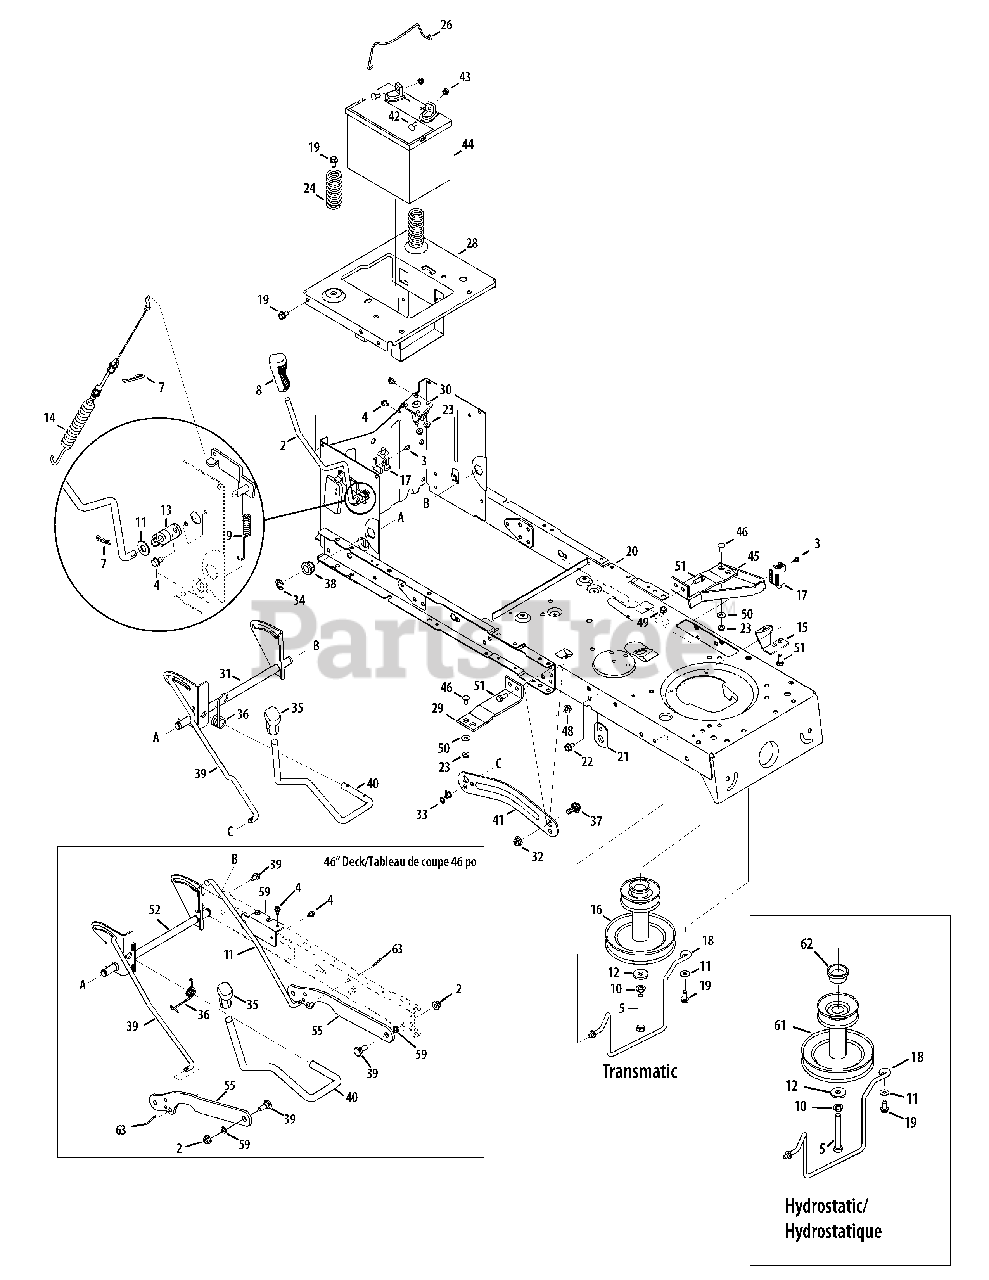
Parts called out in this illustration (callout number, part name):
2	PTO Handle
3	Shoulder Scr #10-16 x .50" Lg.
4	Hex Wash S-Tapp Scr 1/4-20 x .50
5	Hex Hd. Cap Scr. 7/16-20 x 3.25 Gr. 5
6	Frame Brace Bracket
7	Bow Tie Cotter Pin
8	Handle Grip 3/8
9	Extension Spring
10	Lockwasher 7/16 ID
11	Flat Washer .385 ID x .87 OD x .06
12	Flat Washer .450 x 1.25 x .164
13	PTO Bearing
14	Deck Engagement Cable
15	Frame Support Bracket
16	Engine Pulley 3.39 x 6.12 dia.
17	Interlock Switch
18	Belt Keeper Rod (38" Deck)
19	S-Tapp Scr 5/16-18 x .75
21	Pedal Support Bracket
22	Hex Wash HD TT Scr 5/16-18 x .625
23	Hex L-Flanged Nut 1/4-20 Gr. F, Nylon
24	Compression Spring 1.28 x 3.125
26	Battery Hold Down Rod
28	Seat Frame Bracket
29	Running Board Bracket
30	Solenoid
31	Lift Shaft (38" & 42")
32	Flange Lock-Nut 3/8-16 Gr. F, Nylon
33	Cotter Pin .08 x 1.56 Intern - R.H.
33	Cotter Pin .08 x 1.25 Intern - LH
34	"E" Ring .625 Dia.
36	Torsion Spring (38" & 42")
37	Shoulder Screw .625 x .175, 3/8-16
38	Hex Flange Bearing .630 ID
40	Deck Lift Han dle(38" & 42")
41	Deck Lift Arm RH
41	Deck Lift Arm LH
42	Hex Flg. Scr. 1/4-20 x .75 Gr. 5
43	Sems Hex Nut 1/4-20
44	Battery 245 CCA (Dry)
45	Support Bracket Ass'y
46	Carriage Bolt 1/4-20 x .62
47	Screw, 5/16-18 x .625
48	Hex L-Flg Nut 5/16-18 Gr. F, Nylon
49	Hex L-Nut 5/16-18
50	Flat Washer .28 x .74 x .063
51	Hex Screw 5/16-18 x .75
52	Lift Shaft (46" only)
53	Cotter Pin 1/8" x 1.0
56	Torsion Spring (46")
57	Flat Washer .395 x .62 x .063
58	Deck Lift Handle (46")
59	Brace Bracket
60	Deck Lift Arm (46")
